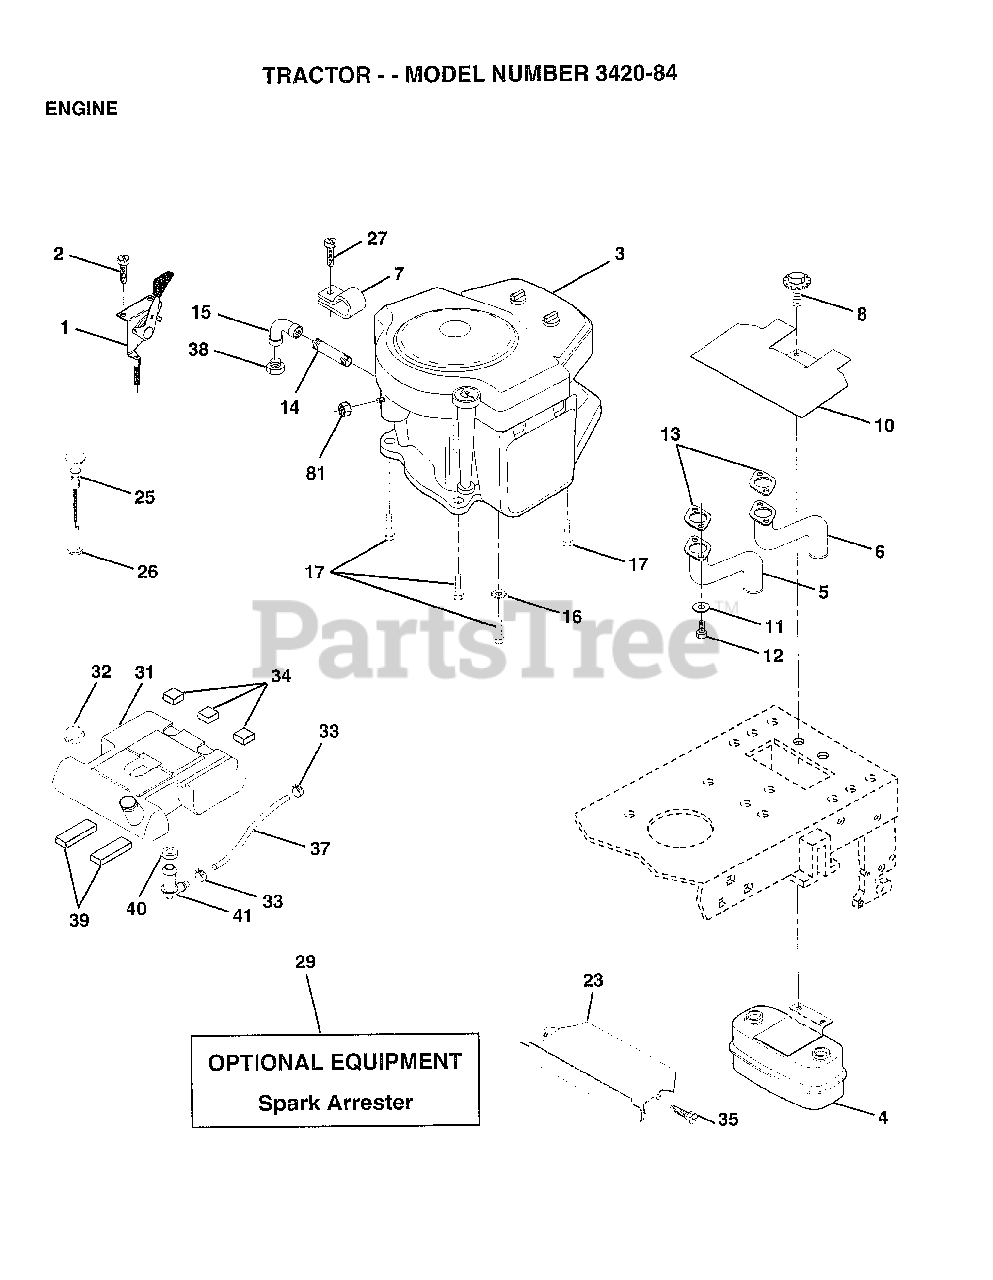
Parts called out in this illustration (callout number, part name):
2	SCREW LT
4	MUFFLER.TW.LOTONE
5	EXHAUST.B&S.18.LH
6	EXHAUST.B&S.18.RH
7	CLAMP.TUBE.DBL.EN
8	BOLT.5/16-18.UNC
10	SHIELD.HEAT.
11	LOCKWASHER
13	GASKET MUFFLER
14	PIPE NIPPLE LT
15	ELBOW
16	LOCKWASHER
17	SCREW LT
23	SHIELD.BRN/DBR.GD
25	"CONTROL.CHOKE.51"""
26	"NUT,KEPS 3/8-24IM"
27	"SCREW-TT,10-32 FL"
31	TANK FUEL REAR
32	CAP ASM FUEL
33	HOSE CLAMP
34	PAD-SPACER LT
35	SCREW
37	FUEL LINE T
39	PAD IDLER TI
40	BUSHING OUTLET T
41	STEM.TANK.FUEL
81	NUT
